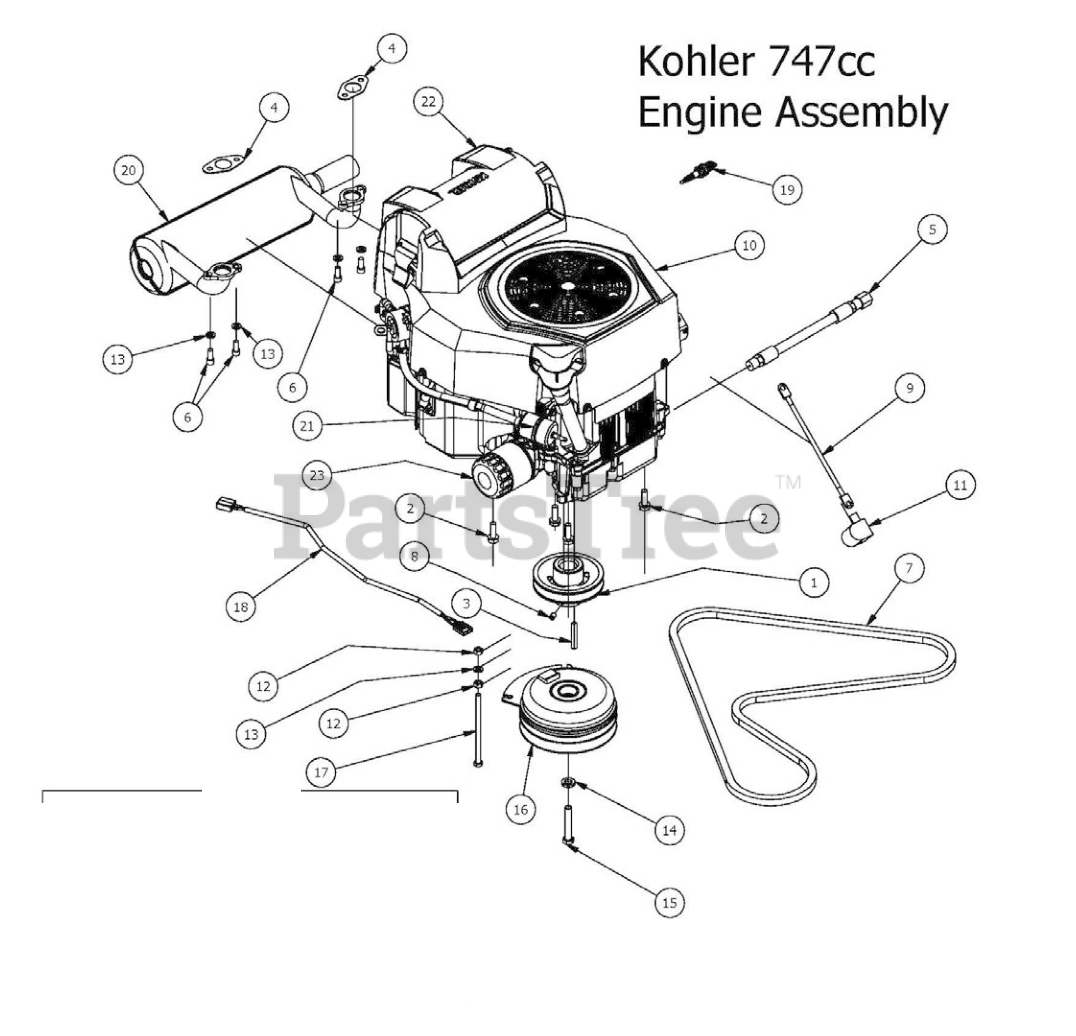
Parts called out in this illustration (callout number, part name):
1	4 3/4 Motor Pulley
2	3/8 x 1 1/8 bolt
3	1/4 x 2 Square key Stock
4	Exhaust Gasket
5	Oil drain Valve
6	5/16-18 x 3/4 Socket C/S
7	75.8 Pump Belt
8	5/16 Set Screw
9	Ground Cable
10	Kohler 747cc Engine
11	Black Boot For Ground Cable
13	5/16" Lock Washer
14	7/16" Lock Washer
15	7/16" x 2 1/2" Hex Bolt
16	Clutch Assembly
17	5/16-18 x 5-1/2 GR 5 Hex Bolt
18	Clutch Pigtail
19	Spark Plug
20	Kohler Muffler
21	Universal Inline Fuel Filter
22	725 Kohler air filter
23	725 & 747 Kohler Oil Filter
